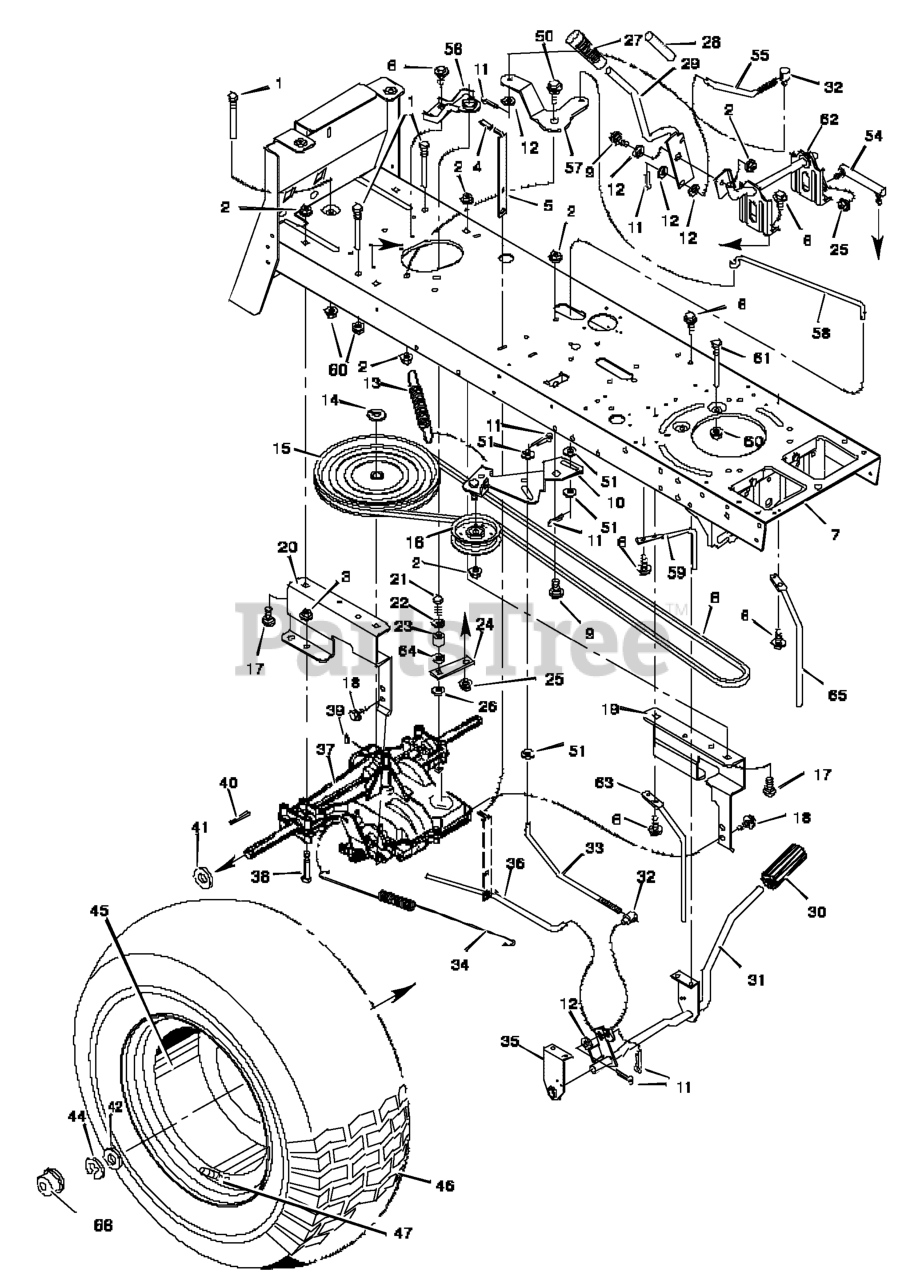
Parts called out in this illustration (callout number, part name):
1	Guide, Belt
2	Locknut, Flange
3	Locknut, Flange
5	Lever, Parking Brake
8	Belt, Motion Drive
9	Bolt, Shoulder
10	Bracket Assembly, Idler
11	Pin, Cotter
12	Washer
13	Spring, Drive Extension
14	Ring, Retainer
15	Pulley, Motion Drive
16	Pulley, Backside Idler
17	Bolt, Carriage
19	Bracket, Left Transaxle
20	Bracket, Right Transaxle
21	Bolt, Hex
22	Lockwasher
23	Pilot, Support
24	Yoke, Shift Lever
25	Locknut
28	Grip, Inner
29	Lever, Shift
30	Pedal, Clutch/Brake
31	Lever Assembly, Pedal
32	Nut, Adjustable
33	Rod, Clutch
34	Spring, Brake Extension
35	Bracket, Pedal Support
36	Rod, Brake Latch
37	Transaxle, Peerless **
38	Bolt, Hex
39	Key, Woodruff No. 9
40	Key, Square
41	WASHER, 1-1.3 16G FLT
45	Wheel & Tire Assembly
46	Tire Only *
47	Valve Stem
50	Bolt, Shoulder
51	Washer
52	Washer
54	Link, Shifter
55	Link, Clutch
56	Bracket, Support
57	Bellcrank
58	Rod, Clutch
59	Guide, Belt
60	Nut, Flange
61	Guide, Belt
62	Shifter Assembly
63	Guide, Belt
65	Guide, Belt
66	Hub Cap
